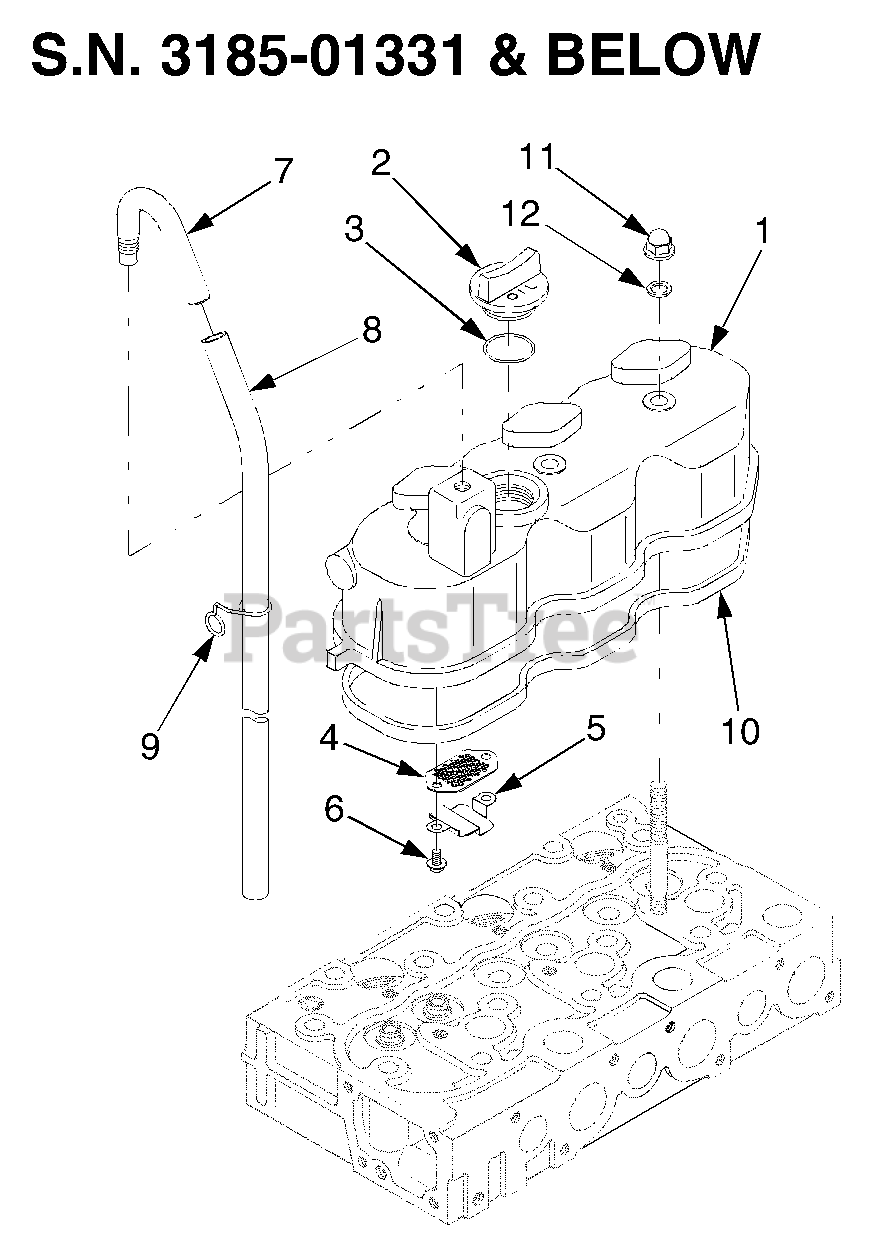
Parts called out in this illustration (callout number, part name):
1	Cover, Cylinder Head
2	Plug, Oil Filler
4	Plate, Element 1
5	Shield, Breather Oil
7	Joint, Breather Pipe
8	Pipe, Breather
10	Gasket, Head Cover
